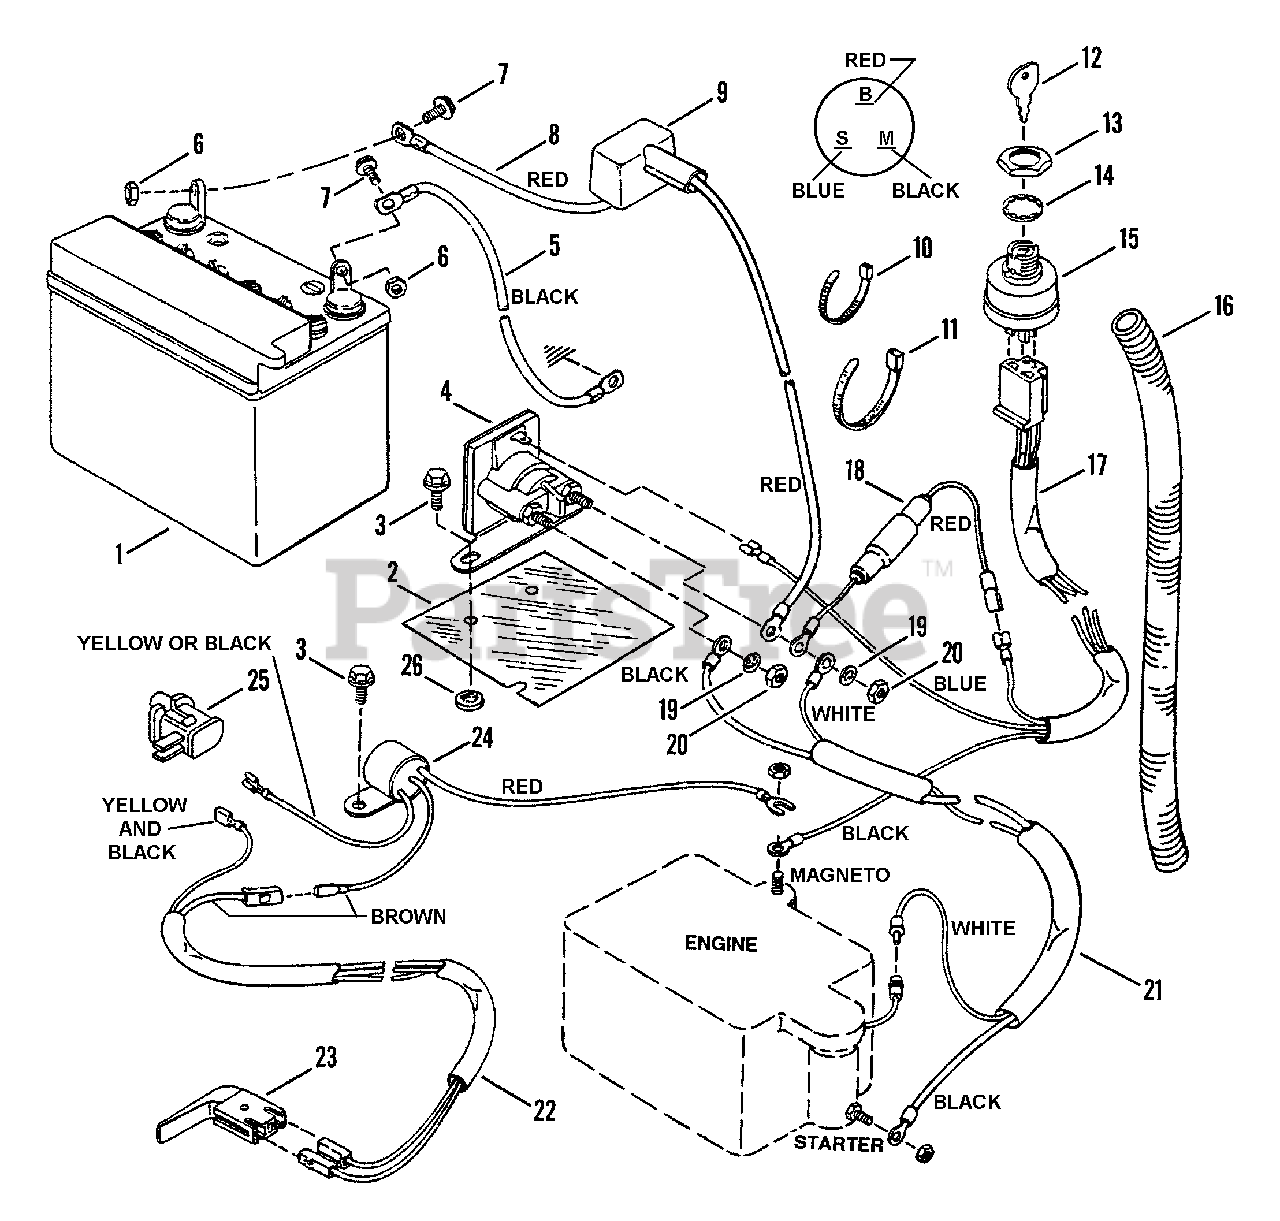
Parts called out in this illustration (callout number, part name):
1	KIT, 12V Dry Charge Battery
2	PROTECTOR, Solenoid
3	SCREW, 1/4-20 x 1/2" Self-Tapping
4	SOLENOID
5	CABLE, Negative
6	NUT, 1/4-20 Hex Lock
7	SCREW, 1/4-20 x 5/8" Hex Head Cap
8	CABLE, Positive (Red)
9	COVER, Battery Cable
10	TIE, Cable (2")
11	TIE, Cable (7")
12	KEY, Switch (With Cover)
13	NUT, 5/8-32 Hex
14	WASHER, 5/8" Internal Tooth Lock
15	SWITCH, Ignition
16	CONDUIT
17	HARNESS, Ignition Wiring (B. & S. Engines)
18	HOLDER, Fuse
19	WASHER, 1/4 Int. Tooth Lk.
20	NUT, 1/4-20 Hex
21	HARNESS, Starter Wiring (B. & S. Engines)
22	HARNESS, Deck Interlock Wiring
23	SWITCH, Deck Interlock
24	INTERLOCK (B.& S. Engines) (Tec = 63065)
25	SWITCH, Seat
26	RETAINER, 1/4 Bolt
